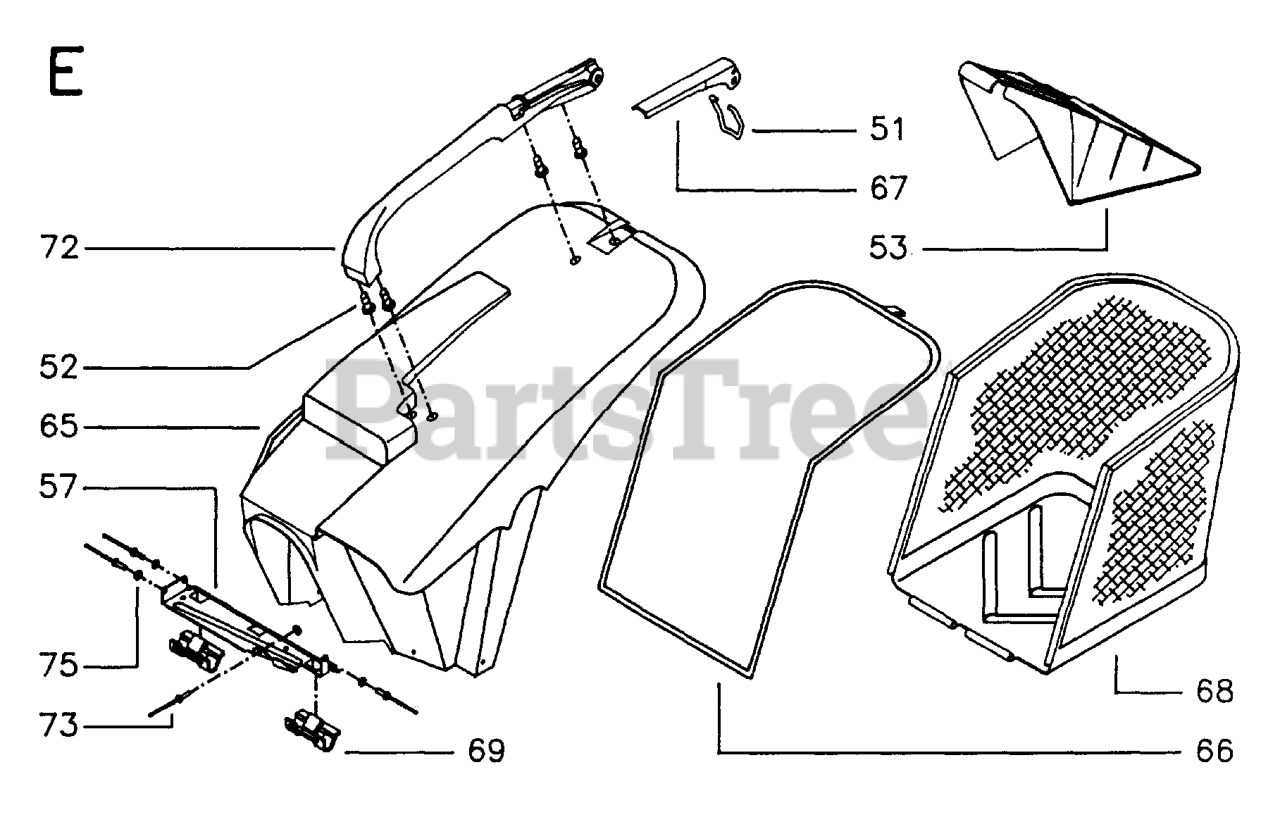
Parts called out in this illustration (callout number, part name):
52	SCREW
53	REPL BY 997 00 85-15
73	REPL BY 516 92 38-00
